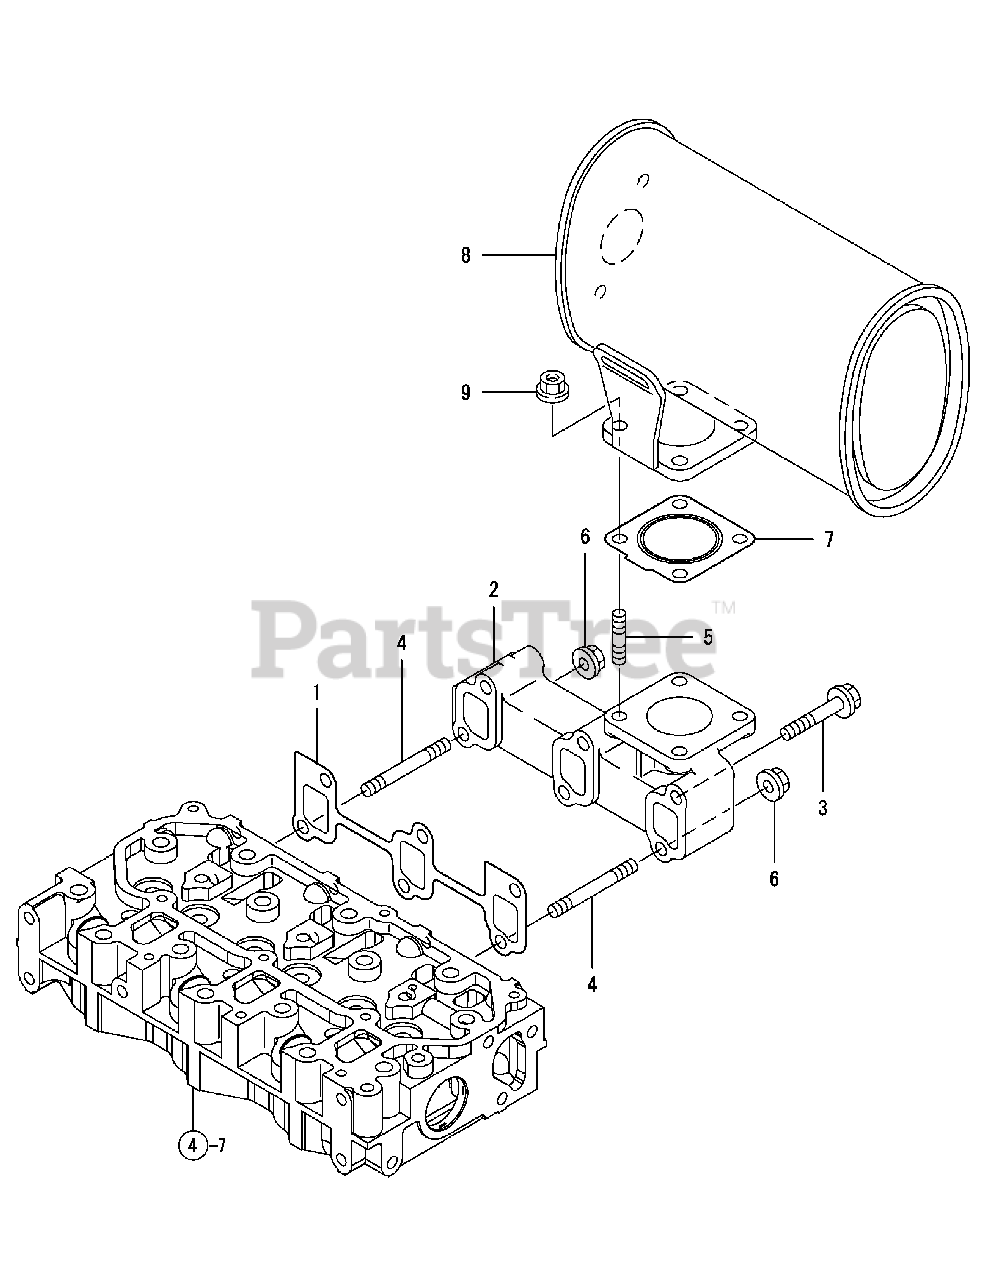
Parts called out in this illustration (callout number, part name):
1	GASKET, MANIFOLD
2	MANIFOLD, EXHAUST
3	BOLT M 8X 50 PLATED
7	GASKET, SILENCER
